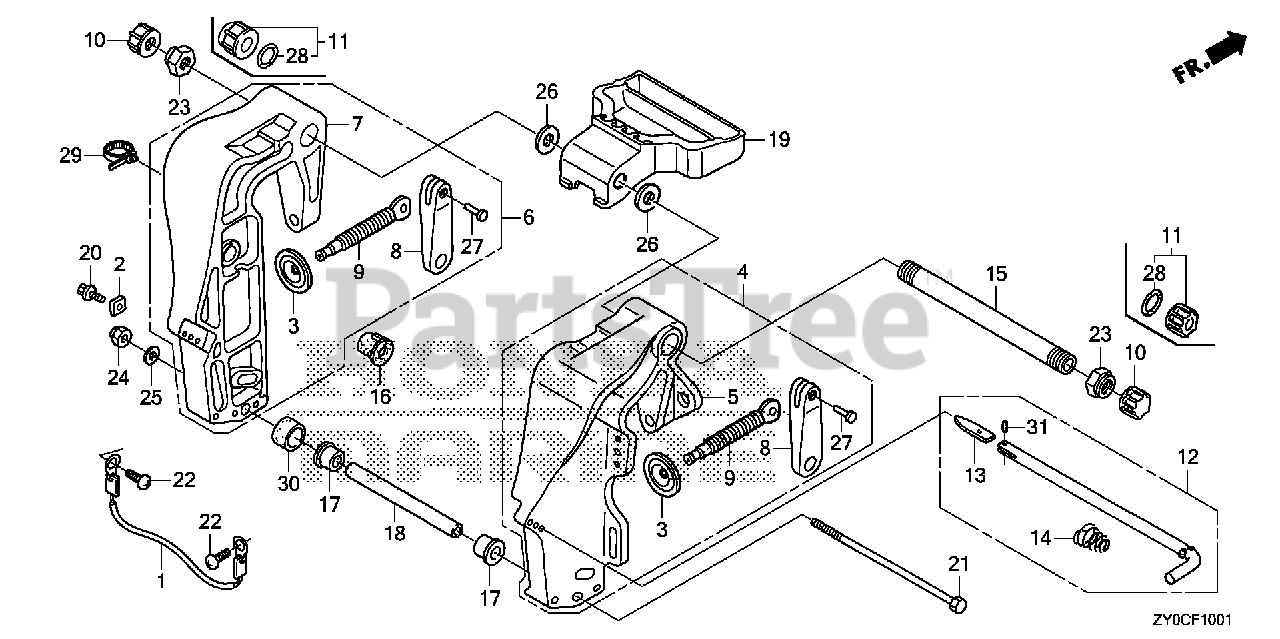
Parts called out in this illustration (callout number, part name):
1	WIRE, LEAD (1.5X170MM)
2	METAL, ANODE
3	PLATE, PUSH
4	BRACKET, R. STERN *NHB14M* (AQUA MARINE SILVER METALLIC)
5	BRACKET, R. STERN *NHB14M* (AQUA MARINE SILVER METALLIC)
6	BRACKET, L. STERN *NHB14M* (AQUA MARINE SILVER METALLIC)
7	BRACKET, L. STERN *NHB14M* (AQUA MARINE SILVER METALLIC)
8	GRIP, CLAMP
9	SCREW, CLAMP
10	CAP, TILTING BOLT
12	ROD, ADJUSTING
13	STOPPER, ROD
14	SPRING, ADJUSTING ROD
15	SHAFT, TILTING
16	BUSH, MOTOR CODE
17	BUSH, CYLINDER (LOWER)
18	COLLAR, CYLINDER (LOWER)
19	HANDLE, CARRYING REMOTE
20	BOLT, FLANGE (6X12) Use from Frame SN 1005249.
21	BOLT, HEX. (8X203)
22	SCREW, PAN (6X8)
23	NUT, SELF-LOCK (7/8-14UNF)
24	NUT, SELF-LOCK (8MM)
25	WASHER, PLAIN (8MM) Use up to Frame SN 4800712.
26	WASHER, WAVE (22MM)
27	RIVET (4X22.6)
29	CLIP, HARNESS BAND (145MM) (BLACK)
30	COLLAR, DISTANCE
31	PIN, SPRING (2.5X8)
